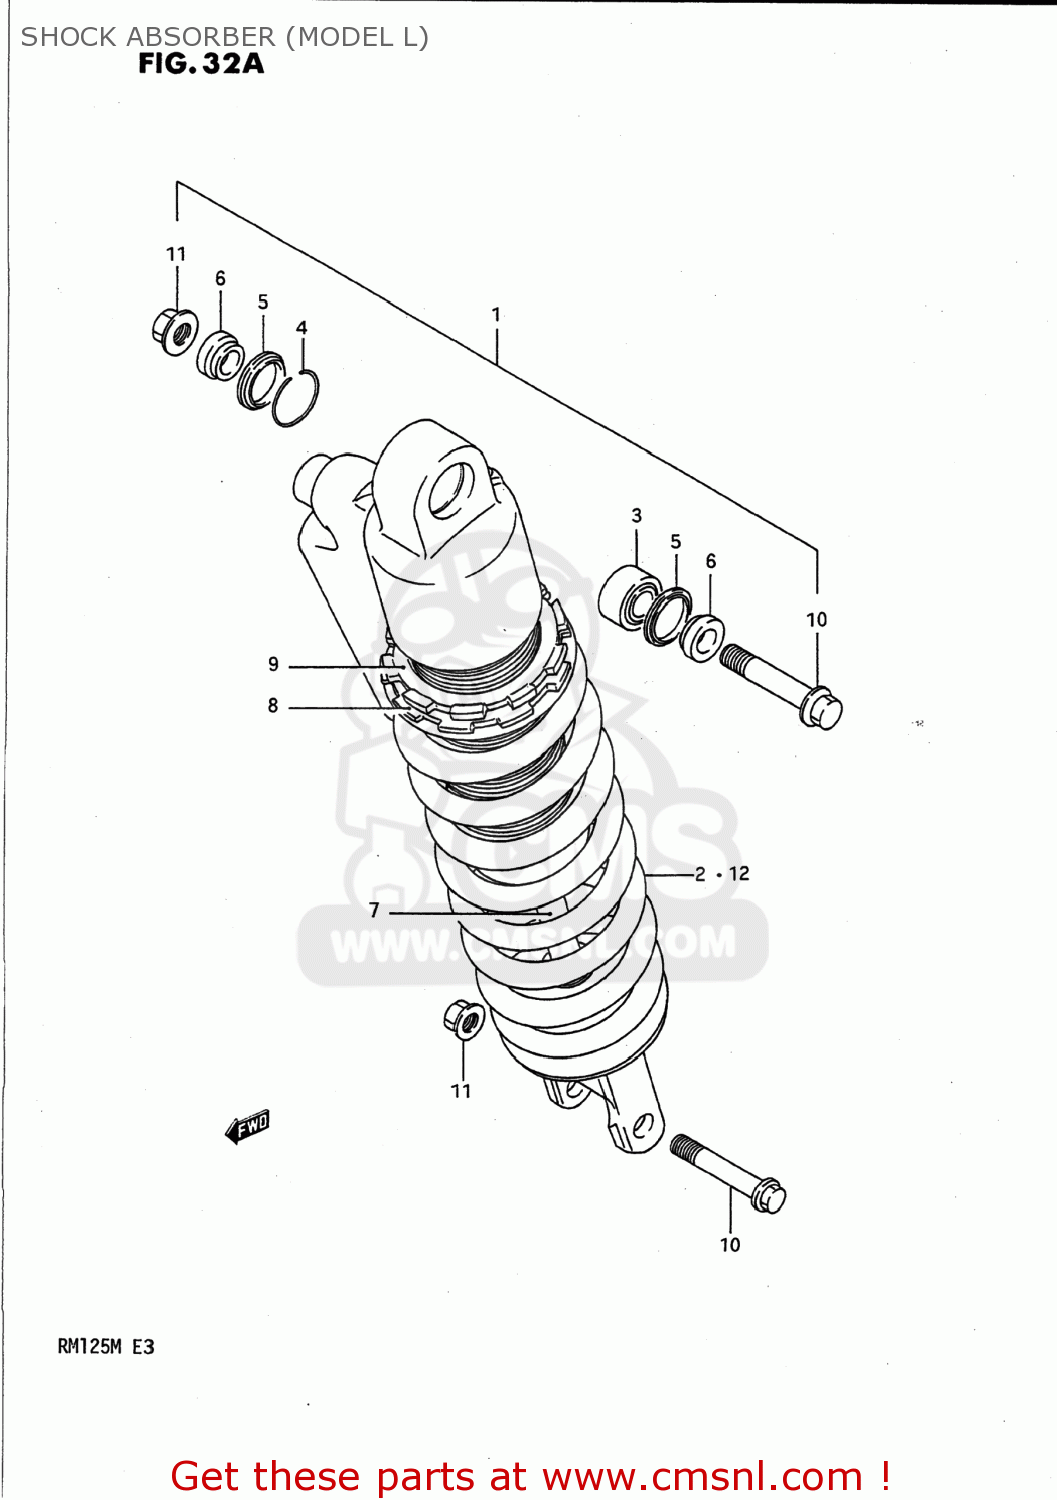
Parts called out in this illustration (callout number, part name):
1	ABSORBER ASSEMBLY,REAR SHOCK
2	SPRING
3	BEARING,RR CUSHION LEVER
4	RING
5	DUST SEAL
6	COLLAR
7	ROD,PISTON
8	GUIDE,SPRING
9	NUT
10	BOLT,REAR SHOCK ABSORBER
11	NUT
12	SPRING
